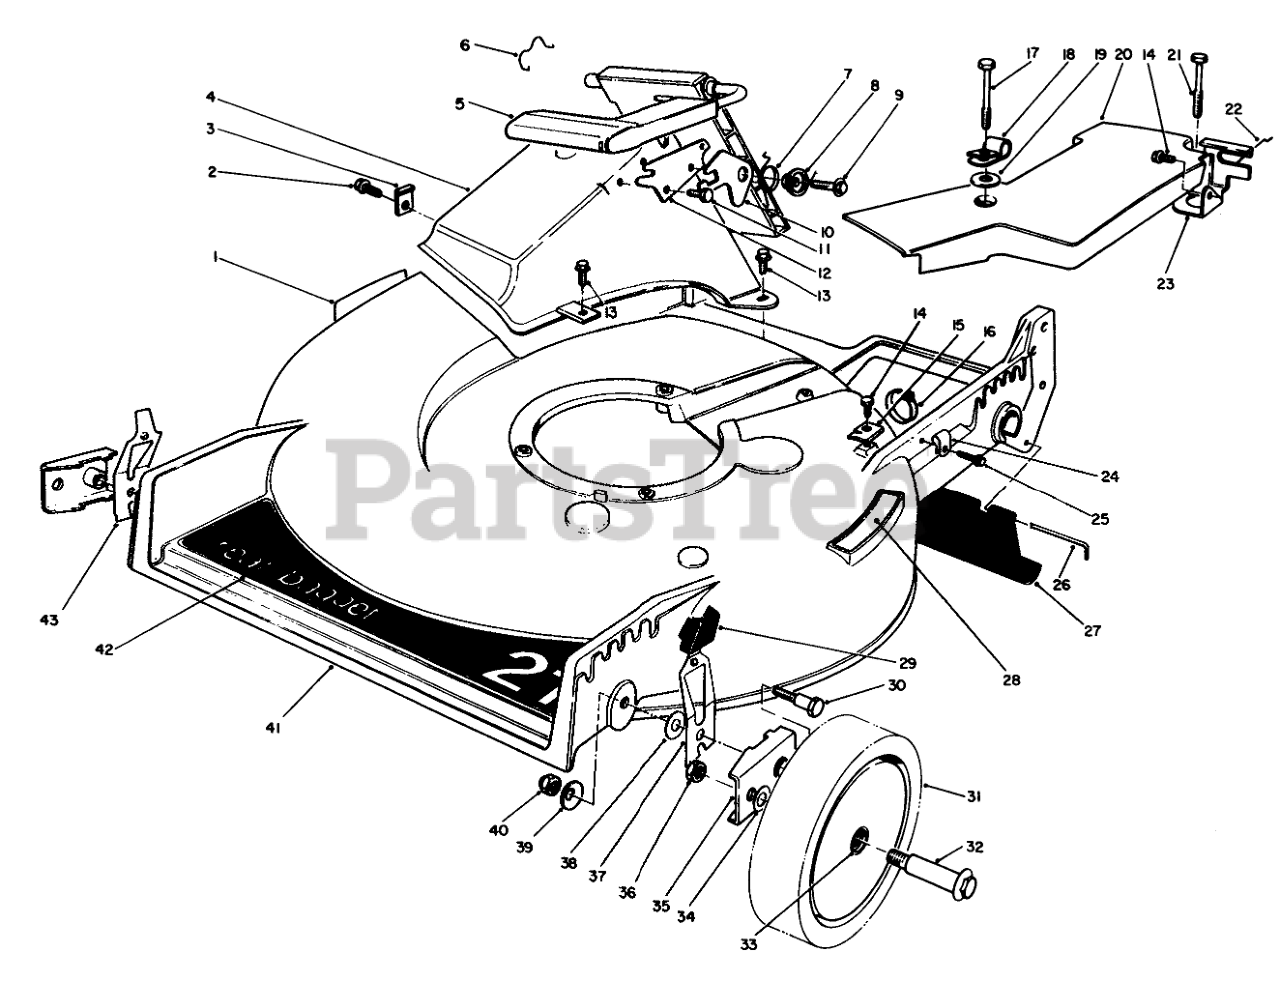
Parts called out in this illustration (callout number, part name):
1	DECAL-DANGER
2	SCREW
3	TUNNEL CLIP
4	Tunnel Discharge
5	Discharge Door Assembly
6	DOOR RET SPRING
7	TORSION SPRING
8	DOOR SPACER
9	SCREW-HWH
10	SAFETY LATCH
11	SCREW-PLASTITE
12	DOOR LATCH PLATE
13	SCREW-HWH
14	SCREW-HWHTF
15	CLAMP-CABLE
16	TIE-CABLE
17	SCREW-SPECIAL
18	CLAMP-CABLE
19	WASHER
20	Belt Cover
21	SCREW-HHFTF
22	RETAINER-CABLE
23	Bracket-Traction Adj.
24	CLAMP-CABLE
25	SCREW
26	ROD-SHIELD
27	SHIELD-TRAILING
28	STEP PAD DECAL
29	KNOB-ARM
30	PIVOT SCREW
31	Wheel & Tire Assembly (Incl. Ref. #33)
32	BOLT-WHEEL
33	BUSHING
34	WASHER
35	HP PIVOT ARM ASM
36	Nut
37	L. HP SPRING ARM ASM
38	WASHER-PIVOT
39	WASHER-BELLEVILLE
40	NUT-LOCK, NI
41	Housing (Incl. Ref. #1, 13 & 28)
42	DECK DECAL
43	R HP SPRING ARM ASM
